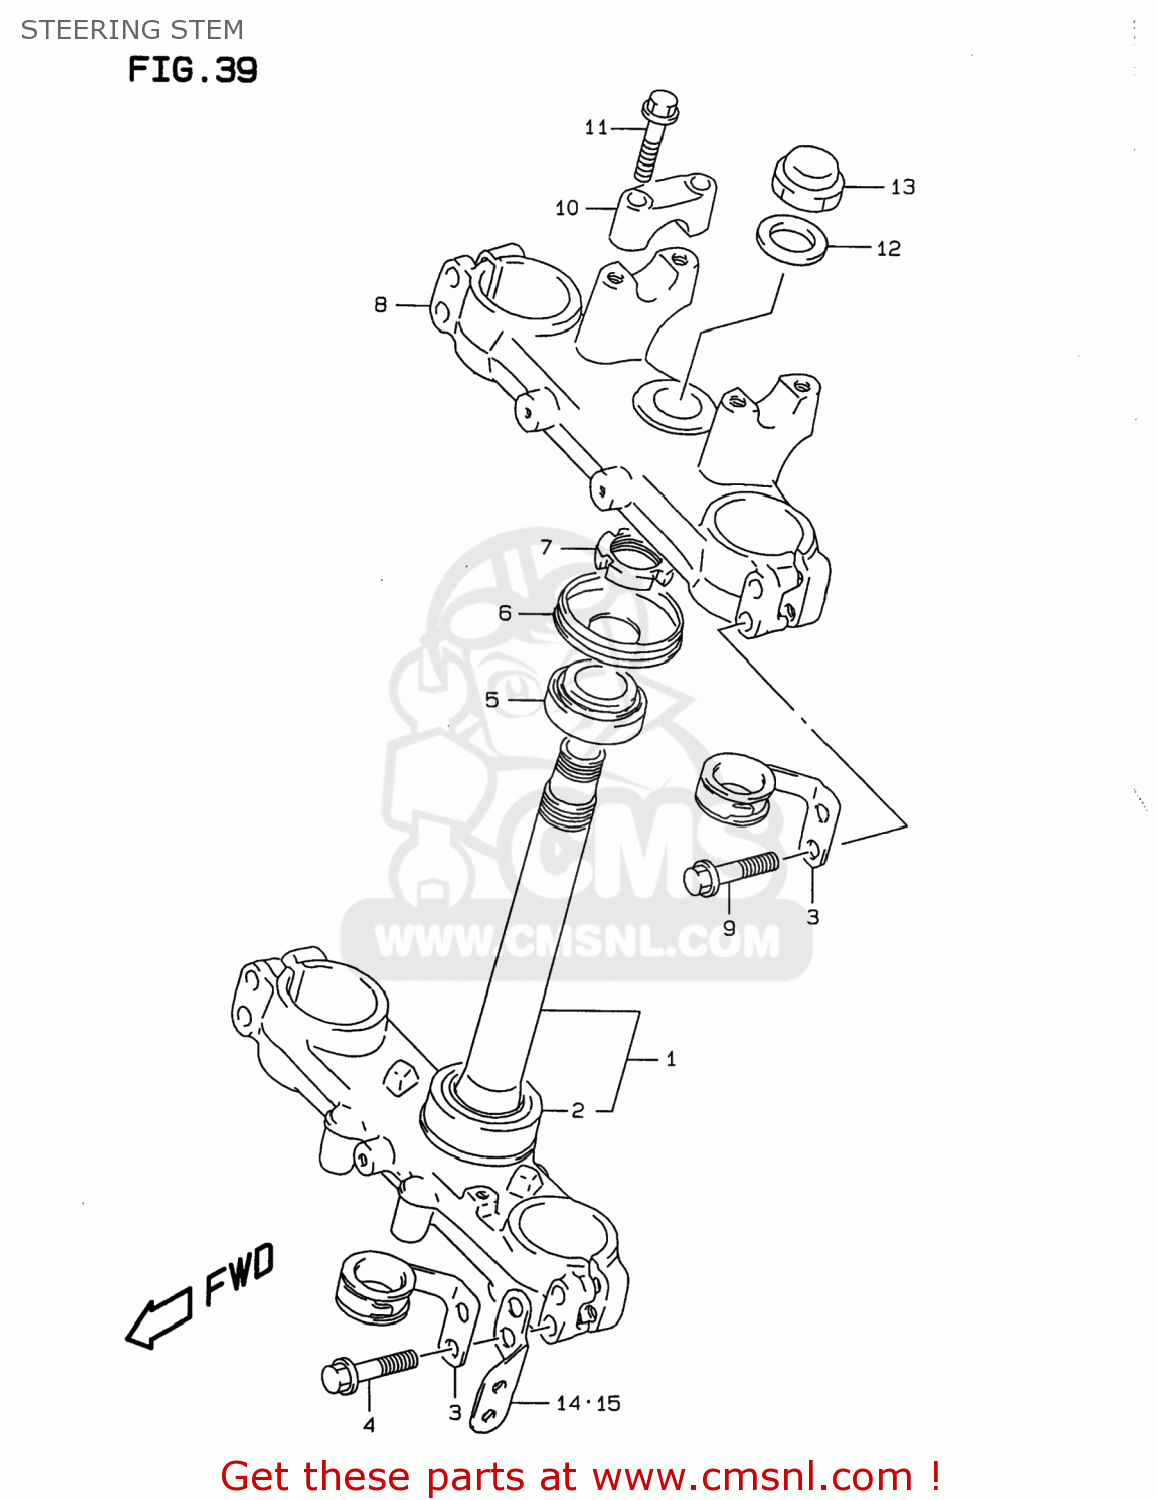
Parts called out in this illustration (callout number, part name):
1	STEM,STEERING
2	BEARING(30X55X17)
3	GUIDE,CABLE LWR,L
4	BOLT
5	BEARING(25X47X15)
6	SEAL,STEERING UPR DUST
7	NUT,STEERING STEM
8	HEAD,STEERING STEM
9	BOLT
10	HOLDER,HANDLE UPR
11	BOLT
12	WASHER
13	NUT,CAP
14	BRACKET,FRONT SIDE REFLECTOR
15	BRACKET,FR SIDE REFLECTOR,L
